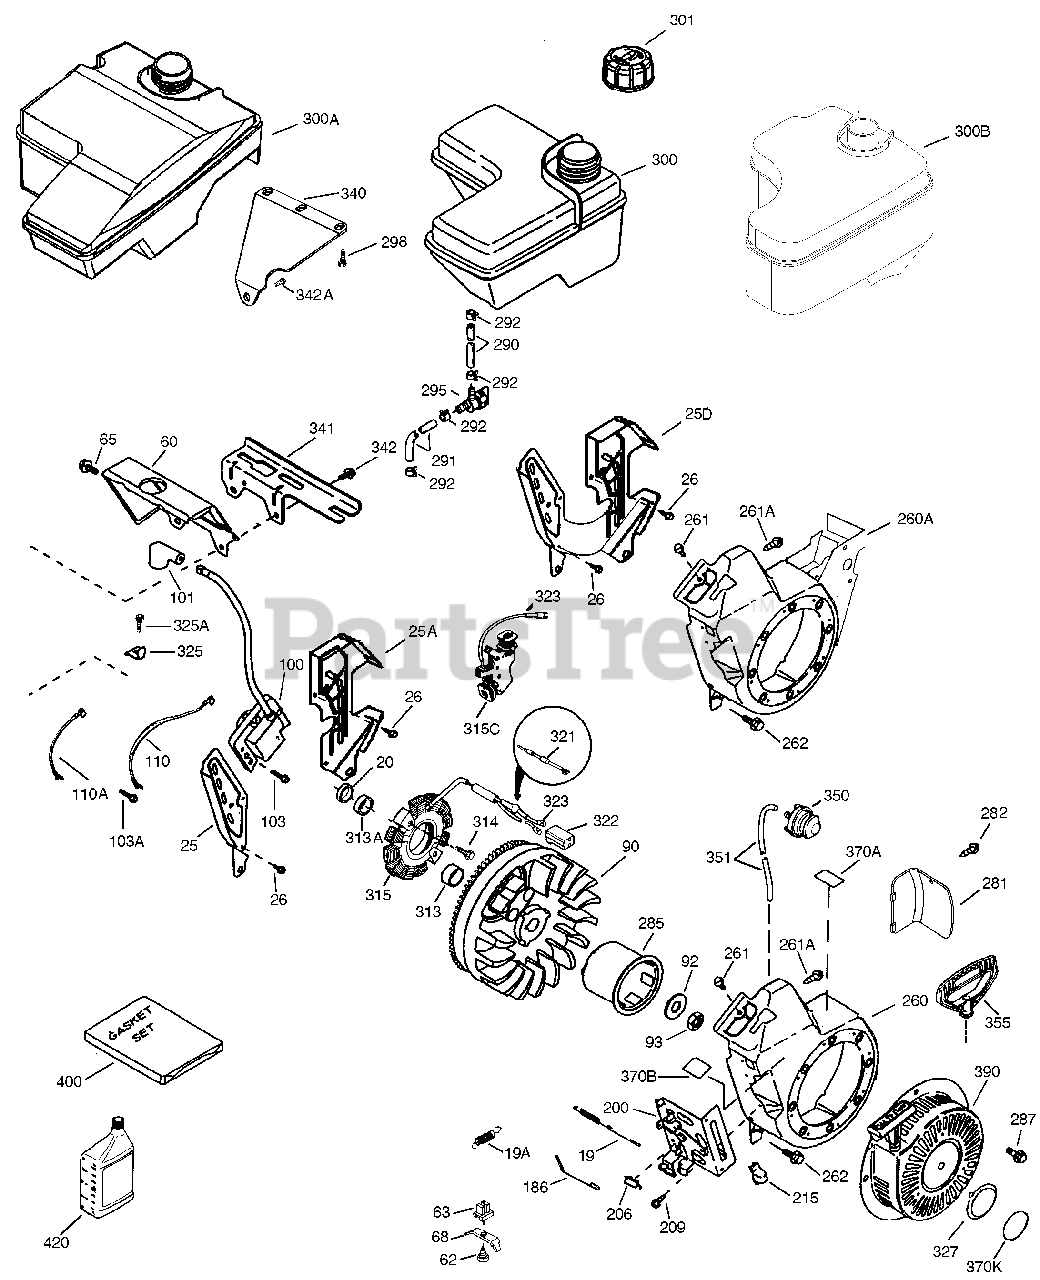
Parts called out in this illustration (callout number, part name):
19	Throttle Spring
20	Oil Seal
25	Air Baffle (Left)
25B	Air Baffle (Right)
60	Blower Housing Extension
65	Screw, 10-24 x 9/16"
66	Screw, 1/4-20 x 27/32"
90	Flywheel
92	Belleville Washer
93	Flywheel Nut
100	Solid State Ignition
101	Spark Plug Cover
103	Screw, T-15, 10-24 x 15/16"
110	Ground Wire - Green, 9.0''
110A	Ground Wire - Green, 5.5''
186	Governor Link
200	Control Bracket (Incl. 206)
206	Terminal
211	Screw, 10-32 x 3/8"
215	Control Knob
229	Nut, 1/4-20
229	Nut & Lock Washer
260	Blower Housing
285	Starter Cup
290	Fuel Line
292	Fuel Line Clamp
300B	Fuel Tank (Incl. 292 & 301) (3.5 Quar t)
301	Fuel Cap (Red)
314	Screw, 1/4-20 x 3/4"
315C	Alternator Coil (18 Watt)
325	Fuel Line Bracket
327	Starter Plug
341	Fuel Tank Bracket (Lower)
342	Screw, 1/4-20 x 7/8"
350	Primer Assembly (also available in Pa ckaged Part #740101) also available i n Packaged Part #740101
351	Primer Line
355	Starter Handle (Mitten Grip) also ava ilable in Packaged Part #740053B
370	Decal - Primer - International Symbol
370	-1
370	Decal - Speed Control - ChokeKey
370	Warning Decal (Bilingual)
390	Rewind Starter NOTE: This engine cou ld have been built with 590733 starte r.
400	* Gasket Set Incl. items marked PK in n otes
701	Screw, 1/4-20 x 31/64"
900	Replacement Short Block, order from 7 1-999Replacement Engine, None
999	Winter Maintenance Kit incl. 5W30 Oil , Spark Plug, Key & Ultra-Fresh
999	Winter Maintenance Kit (incl. 0W30 Sy nthetic Oil, Spark Plug, Key & Ultra- Fresh)
